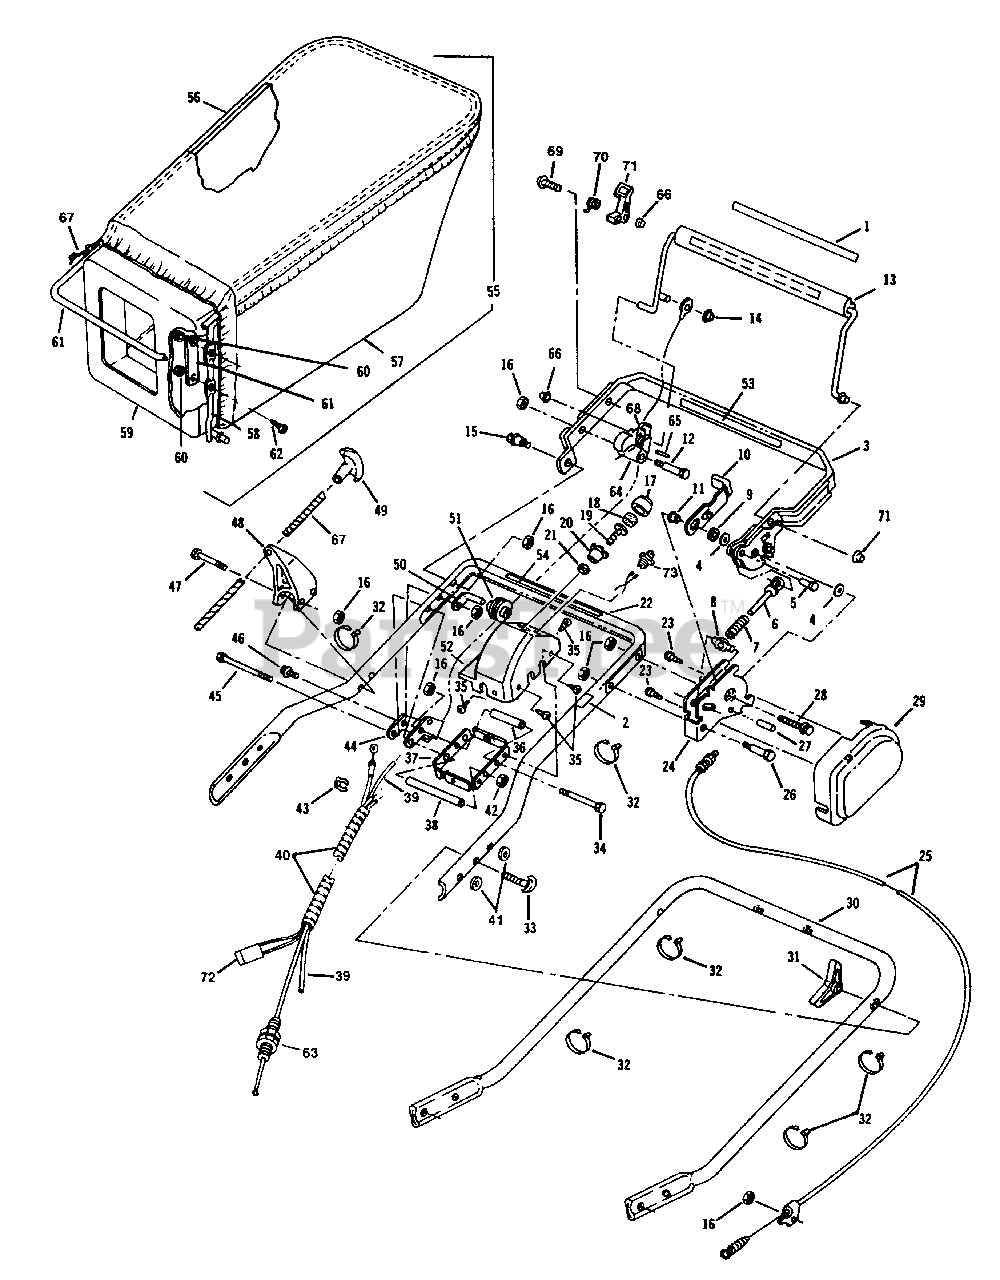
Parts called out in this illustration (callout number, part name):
1	Decal-Engine/ Blade
2	Decal-Drive Lockout
3	Top Handle and Grip Assembly
4	Washer-Spring
5	Pin
6	Rod-Spring
7	Spring-Compression
8	Pivot Pin-Spring
9	Washer
10	Lever Lockout
11	Spacer-Flanged
12	Bolt
13	Control Lever and Nut Assem.
14	Nut-Acorn
15	Bolt Shoulder
16	Locknut
17	Primer Bulb
18	Filter
19	Primer Base
20	Cup
21	Locknut
22	Handle Section-Center
23	Screw-Cover
24	Bracket-Control
25	Cable Assembly
26	Bolt-Shoulder
27	Roll Pin
28	Bolt-Shoulder
29	Cover-Lockout
30	Handle-Lower
31	Knob-Folding Handle
32	Tie Strap
33	Screw
34	Screw-Hex Hd. Cap
35	Screw
36	Spacer
37	Plate-Cover Assembly
38	Spacer
39	Tube-Primer
40	Spiral Tubing
41	Washer
42	Jam-Nut
43	Retaining Ring-Cable
44	Bracket-Clutch Cable
45	Screw
46	Screw-Clutch Cable Brk't.
47	Screw-Truss Head
48	Rope Guide Assembly
49	Handle-Starter
50	Pivot Bracket-Pulley
51	Pulley
52	Cover-Primer Housing and Switch
53	Decal-Drive Control
54	Decal-Start Instruct
55	Grass Catcher and Bag Assembly
56	Hanger Bag
57	Grass Bag Assembly
58	Latch Bar Assembly
59	Bag Adaptor
60	Nut-Bag Adaptor
61	Bar-Reinforcing
62	Screw-Bar Adaptor
63	Control Cable Assem.
64	Cam and Roll Pin Assem.
65	Roll Pin
66	Pushnut
67	Rope
68	Cam
69	Screw-Pivot
70	Spring
71	Stop Latch Lever
72	Wiring Harness
73	Rotary Switch
